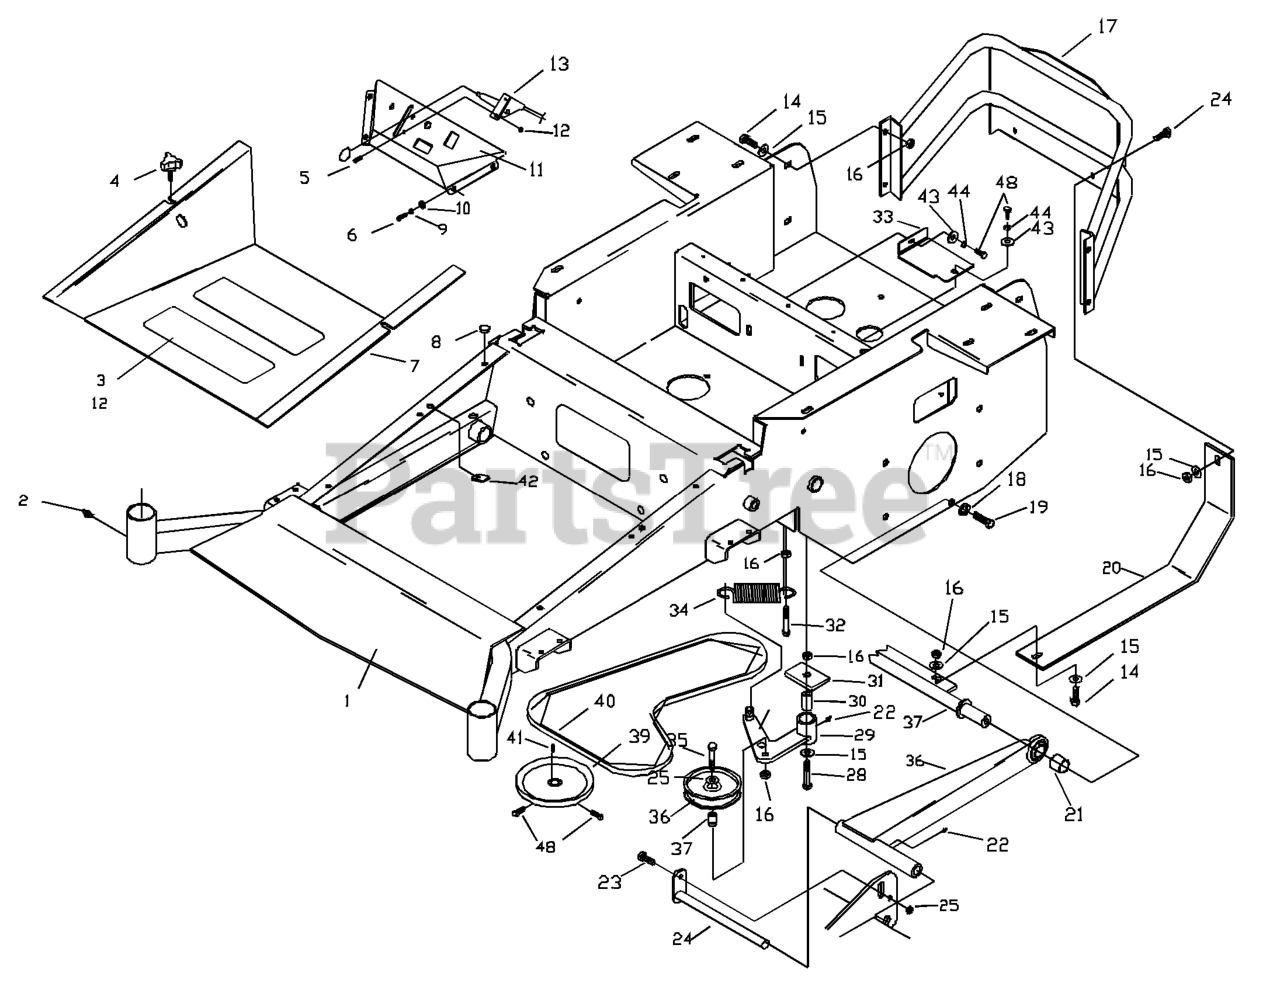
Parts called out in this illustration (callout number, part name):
1	MAIN FRAME W/DECALS
1	FRAME 52" & 61"
2	ZERK
3	ANTI-SKID PAD
4	KNOB W/STUD
5	HCS #10-24 X 1/2
6	SCREW 1/4 X 5/8
7	FOOT PLATE WIDMT
8	GROMMET, BUMPER
9	LOCKWASHER 1/4"
10	WASHER 1/4 FLAT
11	CONSOLE W/DECALS
12	NUT 10-24 NYLOC
13	THROTTLE CONTROL W/BALL KNOB
14	HCS 3/8-16X1.GRD.5.ZD
15	WASHER 3/8 FLAT
16	NUT 3/8C CENTERBLOCK
17	REAR GUARD
18	WASHER 7/16 LOCK
19	HEX SCREW 7/16-14 X 1 GR8
20	SKID PLATE
21	SPACER, STRUT
22	ZERK
23	HCS 5/16C X 3/4
24	PIVOT PIN
25	NUT 5/16C CENTERLOCK
26	STRUT
27	CROSS SHAFT WLD 72
27	CROSS SHAFT WLDMT
28	HCS 1/2C X 3 1/4
29	IDLER ARM WLDT
30	PIVOT BUSHING
32	HCS 3/8C X 1 1/2
33	IDLER COVER
35	HCS 3/8-16 X 1 3/4 GR5
36	IDLER PULLEY
37	BUSHING, IDLER FLANGE
38	SCREW 5/16C X 5/8 SQ HEAD
40	PUMP BELT
41	KEY 5 MM SQ X 25 MM
42	U-CLIP 5/16-18 NUT RETAINER
43	WASHER 5/16 FLAT
44	WASHER.LOCK.HVY.HLCL.SPR.5/16
45	STRUT WELDMENT
46	STRUT PIN RH
47	STRUT SPACER - 72"
48	HCS 5/16C X 1
